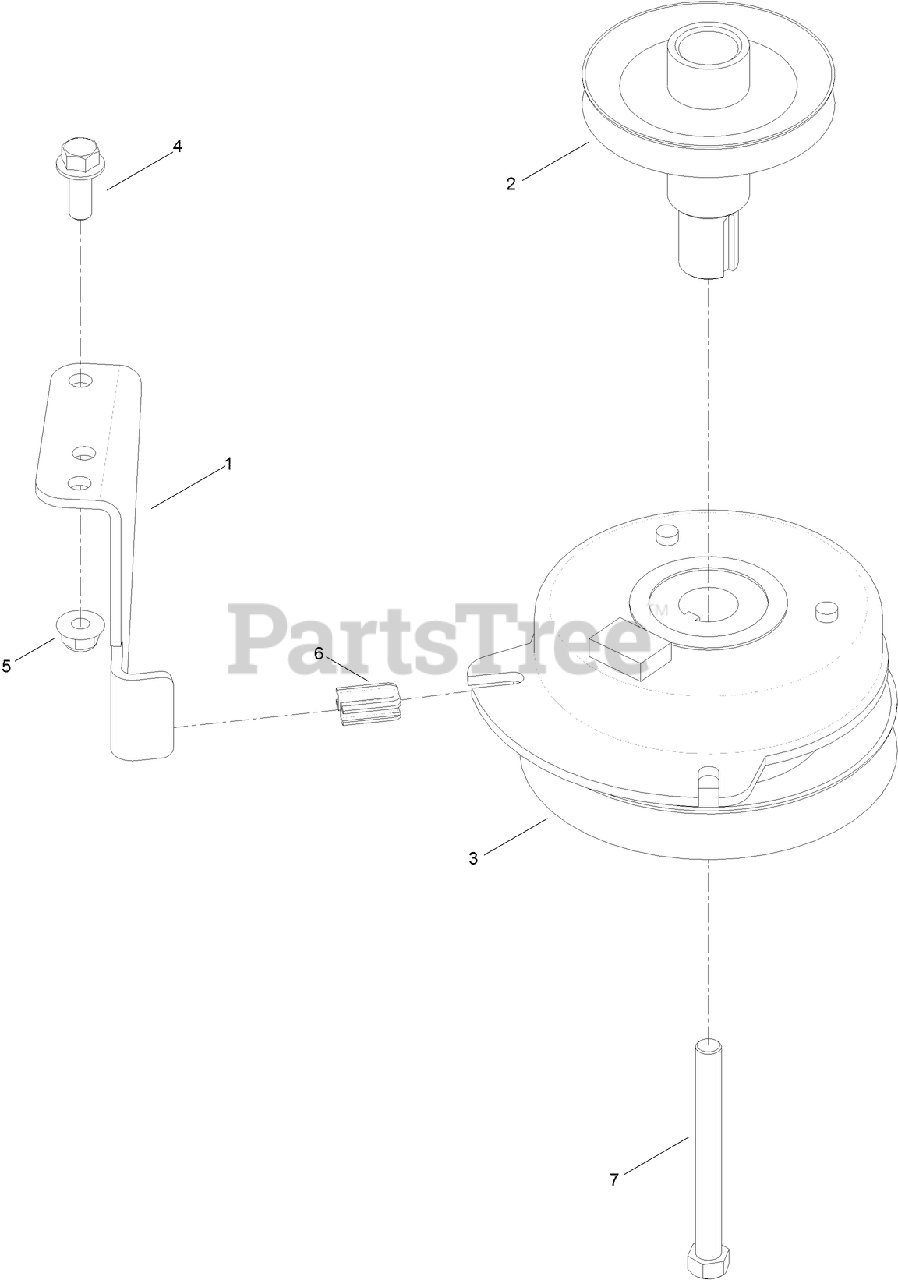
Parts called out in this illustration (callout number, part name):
1	STOP-CLUTCH (WIDE)
2	PULLEY-ENGINE
3	CLUTCH-PTO
4	SCREW-HHF
5	NUT-HF, NI
6	ISOLATOR-CLUTCH
7	SCREW-HH
